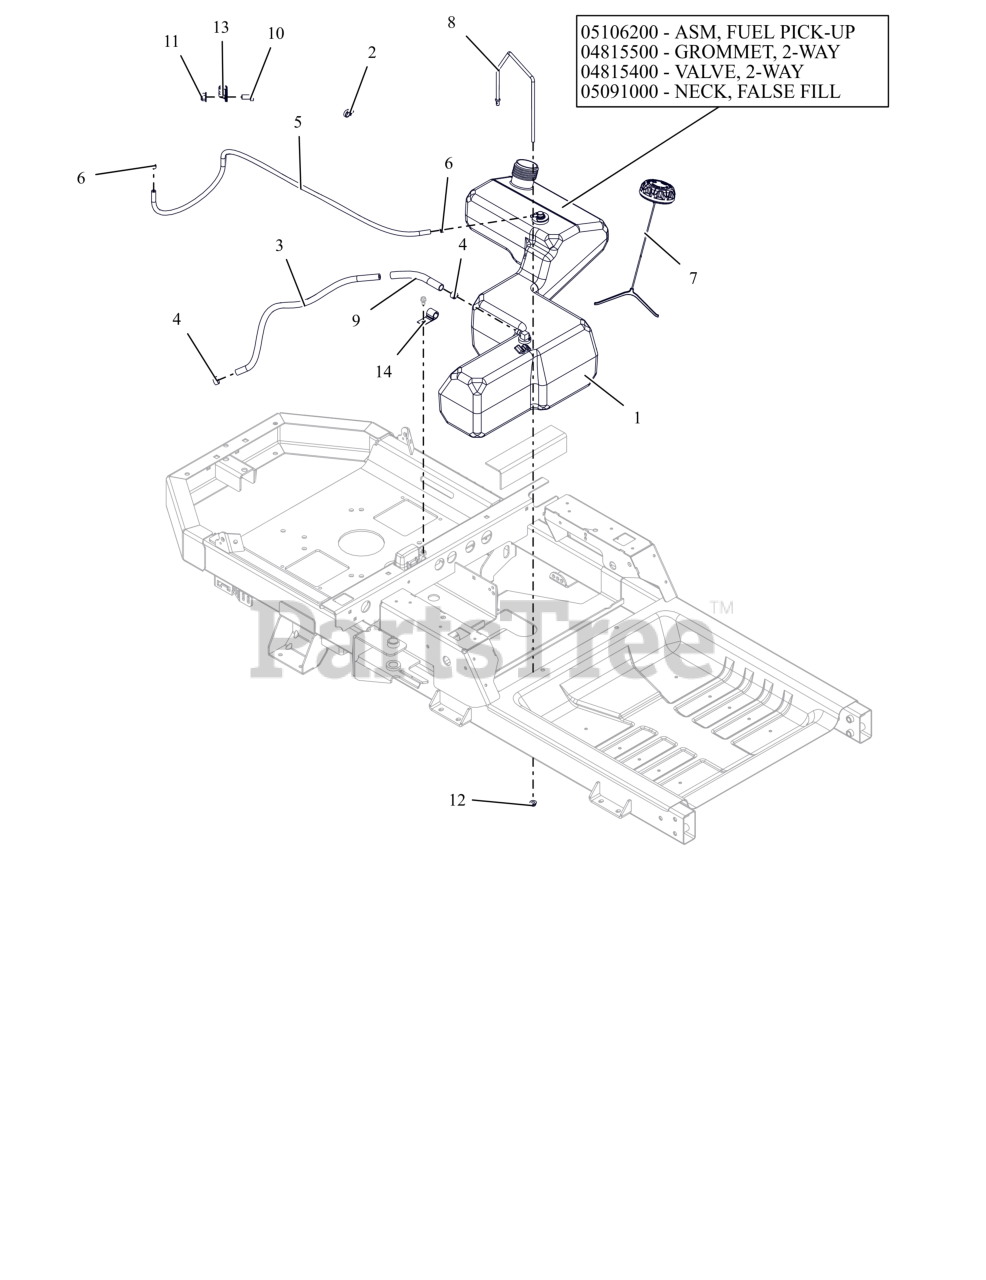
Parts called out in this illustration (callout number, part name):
1	ASM, FUEL TANK-IKON
1	ASM, IKON FUEL PICK-UP
1	GROMMET, 2-WAY
1	VALVE, 2-WAY
1	NECK, FALS FILL - 2017 IKON
2	ROUTING CLIP (1/2" ID)
3	HOSE, .25 LOW-PERM BULK GAS
4	CLAMP, FUEL LINE
5	HOSE, .188 LOW-PERM BULK GAS
6	CLAMP-HOSE, SPRING .188
7	CAP, FUEL VENT-IN 2.25" RATCH.
8	BRKT, FUEL
9	SLEEVE, ANTI ABRASION .5" X .064" WALL
10	BLT,HEX .38-16X.75 G5 ZCC
11	NUT,NYL-FLG .38-16 GF ZCC
12	NUT,NYL-FLG .25-20 GF ZCC
13	CLAMP, CUSHIONED STEEL
